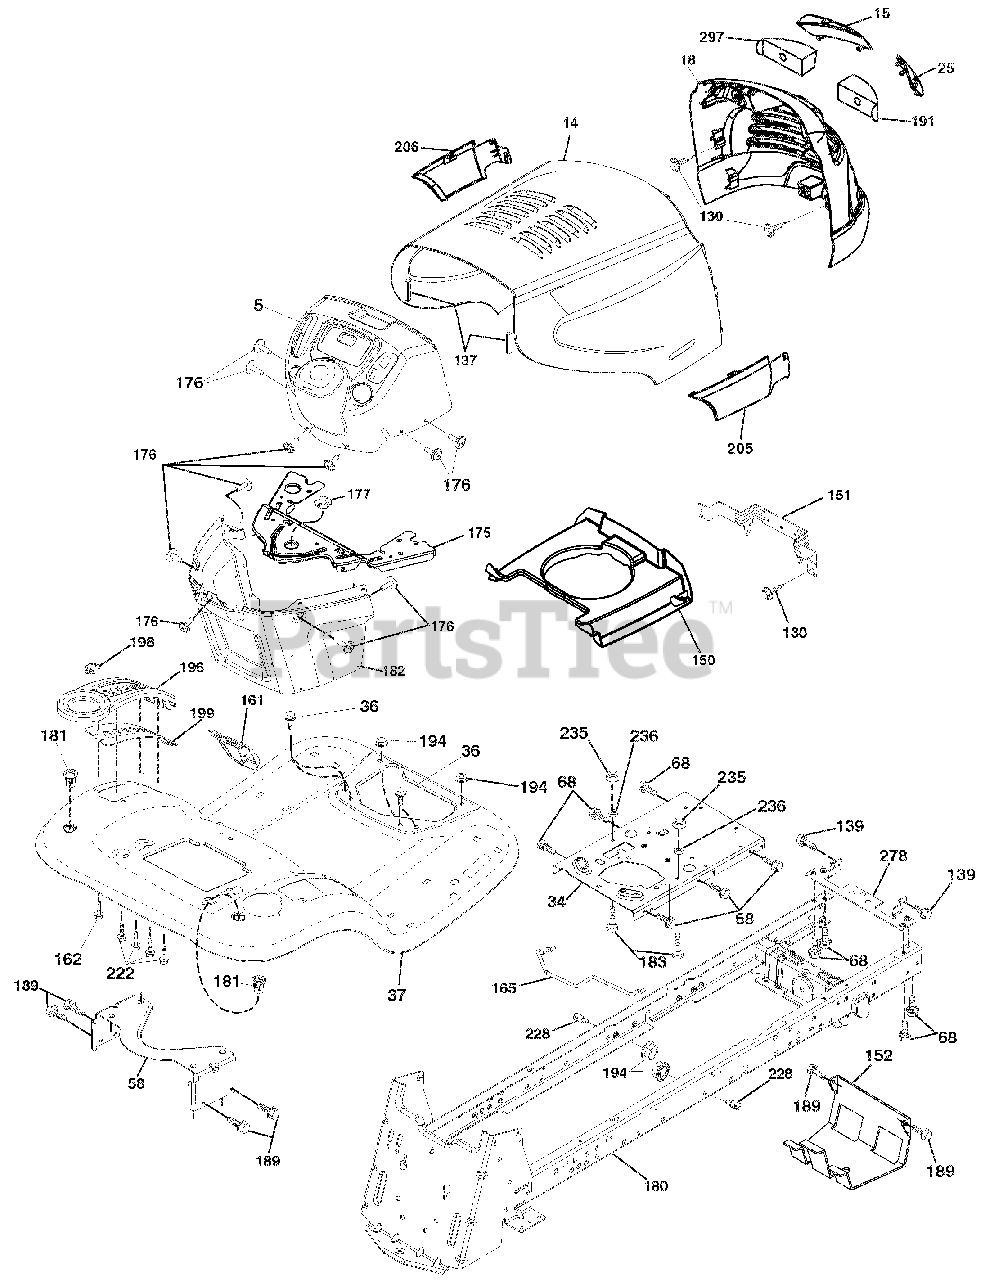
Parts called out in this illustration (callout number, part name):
5	DASH.UPPER.TEX.ELITE.EL.CK.428
15	LENS.ELITE-HUSQ.CLEAR.LH
18	GRILL, ARIENS TRACTOR 432256
25	LENS.ELITE-HUSQ.CLEAR.RH
34	PLATE.ENGINE.WELDED.CHASSIS
36	SCREW.5/16-18X3/4.SMGML.TAP/R
58	FENDER SUPPORT BRACKET
68	SCREW.THDROL.5/16-18 X 1/2TYTT
137	BUMPER.HOOD.LARGE. 1.75"
138	KIT.BUMPER.HD.2009
139	BOLT SHOULDER 5/16-18
150	AIR DUCT.ENGINE.ELITE-SV
151	BRACKET.PIVOT.LASR/ELTE/HUSQLT
152	SHIELD.BROWNING.W/TEX
161	WINDOW FUEL
162	SCREW.HEX.WSH.HI-LO.1/4X1/2UNC
165	SUPPORT.TANK.REAR.W/TEX
175	CROSSMEMBER.LT
176	SCREW.#10-24X5/8.RND.QUDRX.GIM
177	BUSHING.STEERING.YT/GT
180	CHASSIS
181	BUSHING.MNT.FEND.CRGO.BLK.TEX
182	DASH LOWER.LT.CCS
183	BOLT.FIN.HEX.5/16-18 UNC X1-1/
189	SCREW.5/16-18X3/4.SMGML.TAP/BL
191	INSERT.REFLECTIVE.RH.
194	Nut, Lock Hex Flange 5/16-18 u
196	CONSOLE ASM. DECK LIFT
198	INDICATOR.DECK LFT.STGT/LT.505
199	PLATE DECK LIFT
205	SKIRT.SIDE.RH.ELITE HUSQ.428
206	SKIRT.SIDE.LH.ELITE HUSQ.428
222	SCREW.THD.ROLL.1/4-20 X 5/8
228	STUD.FASTNER.W/'D'ANTI-ROTATIO
235	SPACER.FENDER
236	NUT.CENTER LOCK.5/16-18 UNC
278	X-PIECE HOOD
297	INSERT.LENS.RFLCT.ELT-HUSQ.
